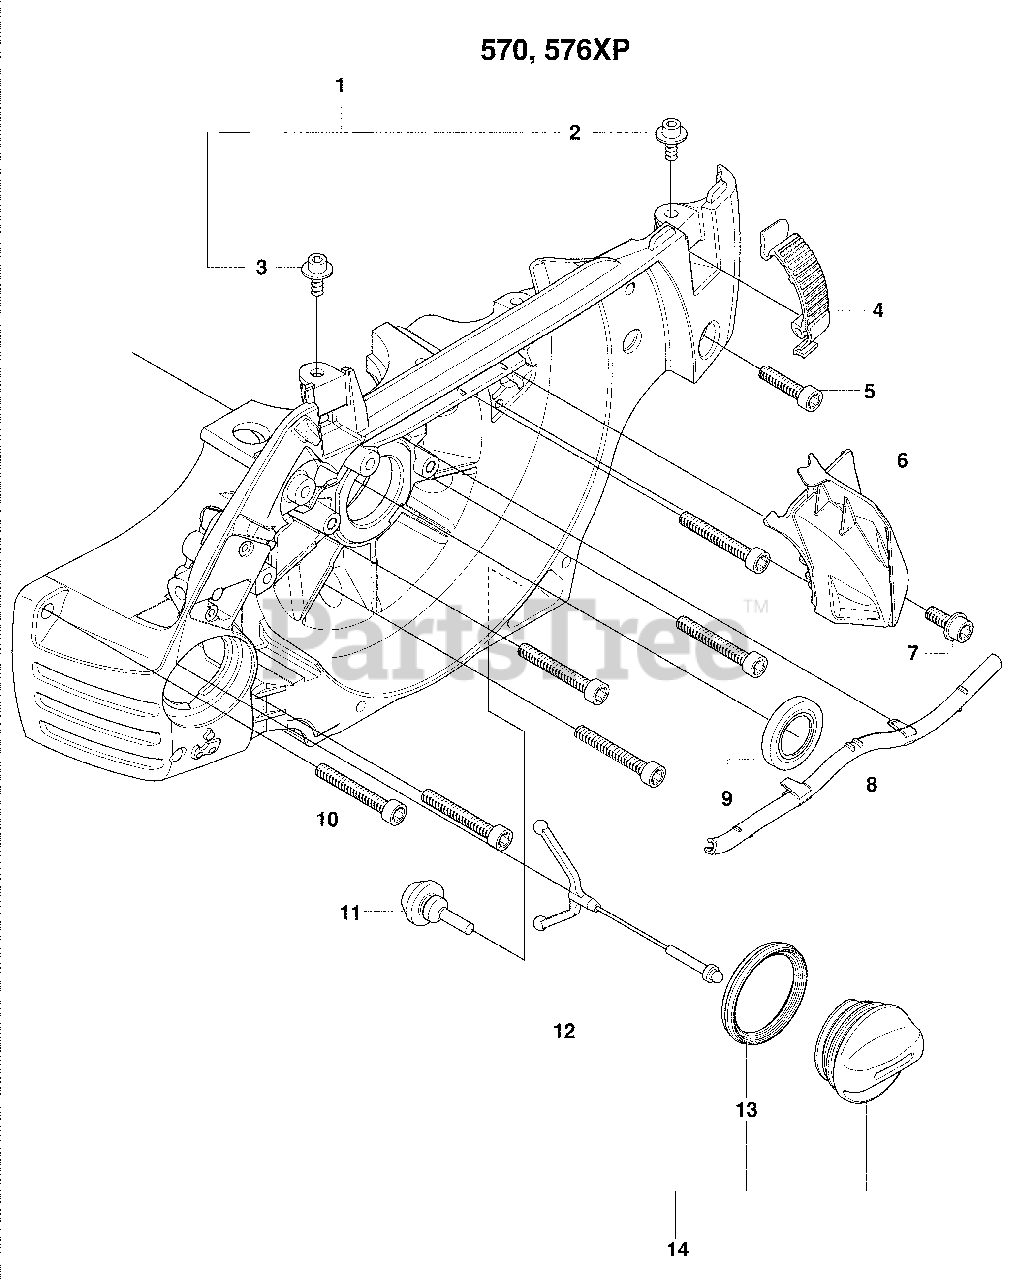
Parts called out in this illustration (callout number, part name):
1	RP CRANKCASE ASSEMBLY
1	CRANKCASE ASSY
4	Top Cover Buckle Clip, Orange
4	Gray Clip
9	Seal Ring
9	Radial Seal
13	Sealing Gasket
14	Fuel and Oil Tank Cap
